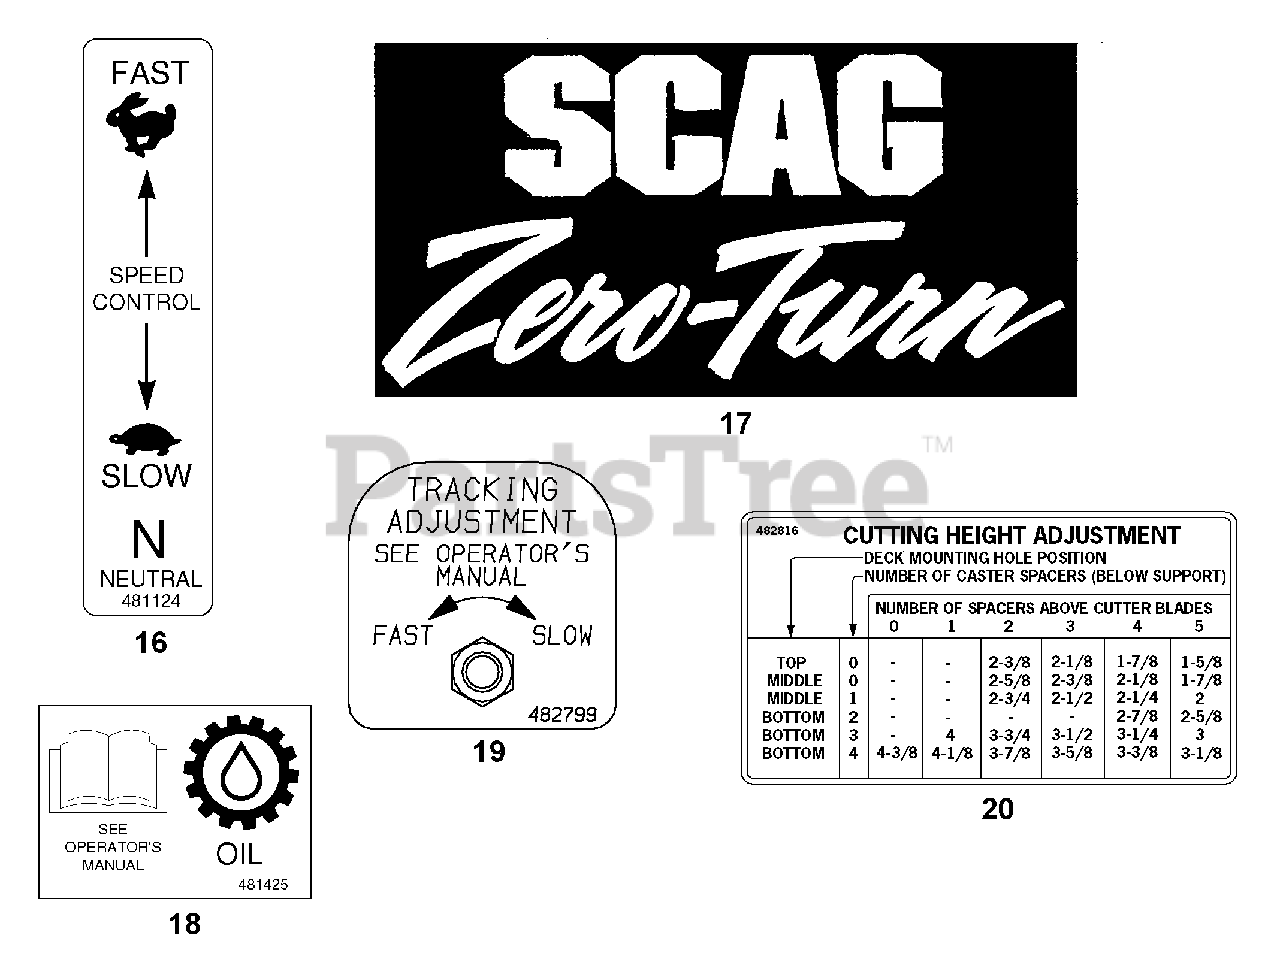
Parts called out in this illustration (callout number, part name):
16	Decal, Speed Control
17	Decal, Scag Zero Turn
18	Decal, Oil
19	Decal, Tracking Adjustment
20	Decal, Height of Cut
